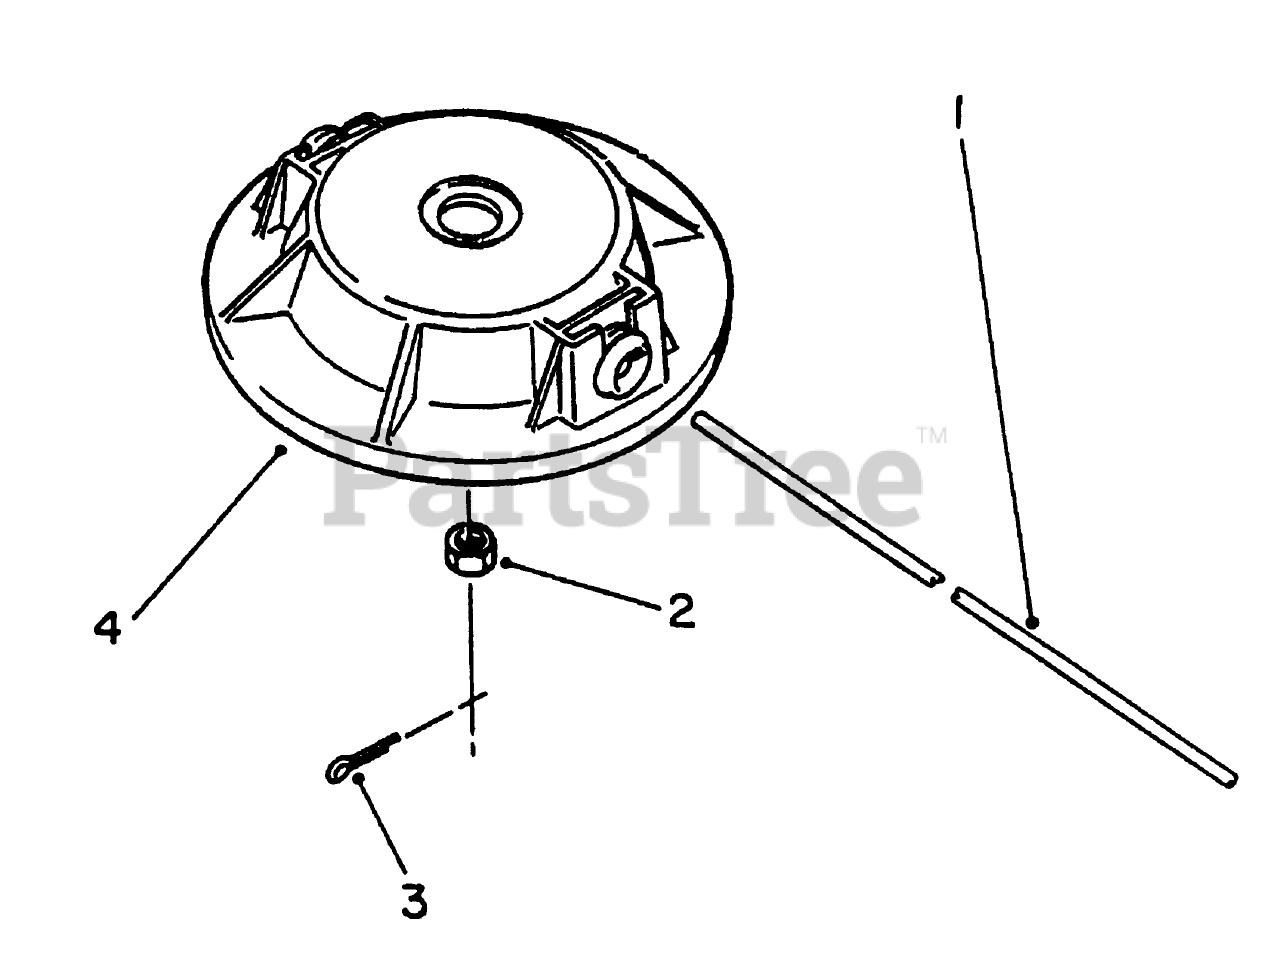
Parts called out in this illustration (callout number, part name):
1	Line-Cutting
3	1/16 X 1 LG COTTER PIN
4	CUTTER HEAD-PLASTIC
